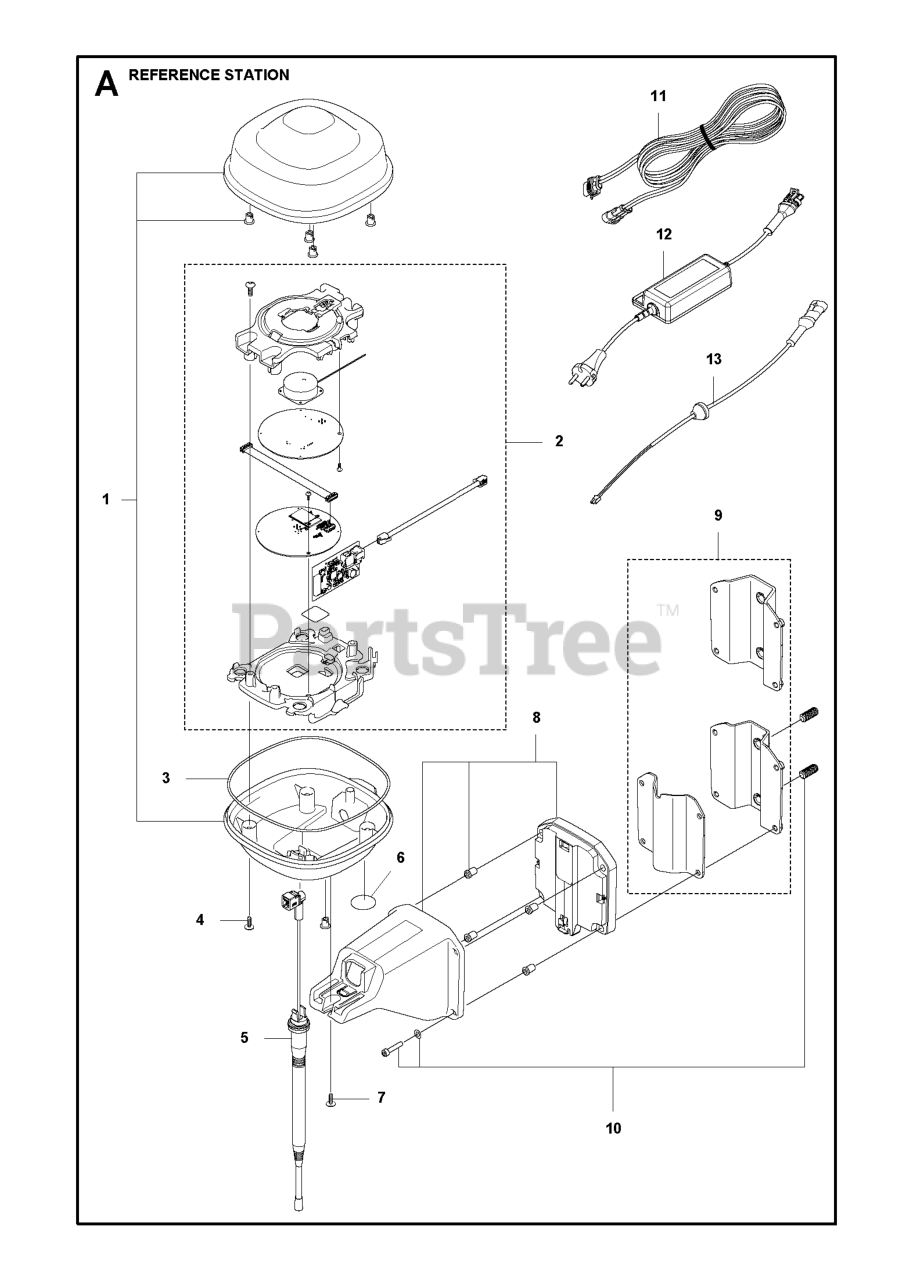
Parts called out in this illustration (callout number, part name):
1	HOUSING ASSY ENCLOSURE SPARES
1	HANDLE
2	PRINTED CIRCUIT ASSY RTK ASSY
2	TUBE
3	SEAL EPDM LOOP REFERENCE STATI
3	SCREW M6X50
3	BOLT
4	SCREW ITXPANM PAN HEAD EPDM SE
4	KNOB
5	ANTENNA ANT ELEV FEED 1/2 DIPO
5	WASHER
6	AIR FILTER P3 SPARES KIT (10)
6	HANDLE
7	SCREW ITXPANM M4X12 A2-70 PAT
7	SPACER PLASTIC
8	ARM ARM ASSY
8	SCREW
9	BRACKET POST FIXING KIT
9	HARNESS HOLDER
10	PACKING ASSY POST FIXINGS KIT
10	NUT
11	CABLE ASSY LOW VOLTAGE CABLE
11	SCREW IHSCFTO
12	Power Unit
12	POWER UNIT POWER SUPPLY 1,3A
13	WIRING ASSY POWER REFERENCE ST
13	DRIVESHAFT 525L
14	LABEL WARNING 110DB/10000RPM
15	DECAL WARNING "NO BLADES"
16	DECAL
17	LABEL WARNING TRIMMERS AND BRU
18	DECAL SPARK ARRESTOR WARNING
19	DECAL START REMINDER 523/525
